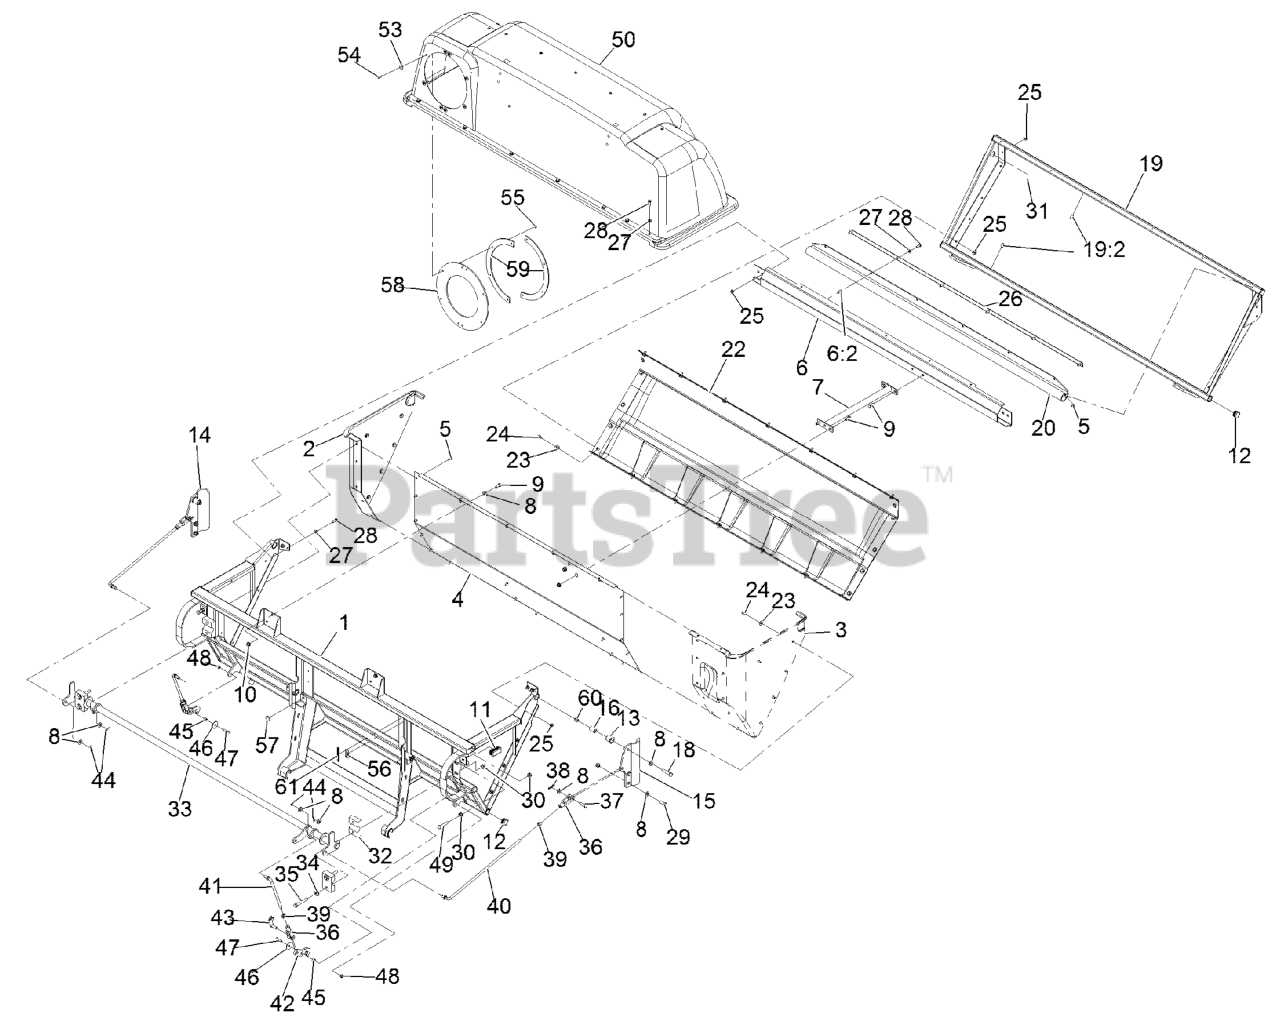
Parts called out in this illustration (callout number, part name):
2	PANEL-BAGGER, RH
3	PANEL-BAGGER, LH
4	SHEET-WALL
5	RIVET-BLIND
6	REAR CROSSMEMBER ASM
6:2	NUT-CLINCH
8	WASHER-FLAT
9	SCREW-HH
13	BUSHING
14	ARM-HINGE, RH
15	ARM-HINGE, LH
16	PIN-PIVOT, HINGE
18	SCREW-HH
19	DOOR ASM
19:2	NUT-CLINCH
20	SEAL-DOOR HINGE
22	BAG AND BOTTOM PANEL ASM
23	WASHER-FLAT
24	SCREW-HH
26	STRAP-HOLD DOWN
27	WASHER-FLAT
28	SCREW-HH
29	SCREW-HH
30	NUT-HHF, WHIZ
31	PLUG-DOME
33	LINK-INTERMEDIATE
34	WASHER-FLAT
35	SCREW-HH
36	YOKE-LINKAGE, BRAKE
37	PIN-CLEVIS
38	PIN-COTTER
39	NUT-HEX
40	LINK-HINGE
41	LINK-HANDLE
43	PIN-SPRING, CLEVIS
44	PIN-COTTER
46	WASHER-FLAT
47	SCREW-HH
48	NUT-LOCK, NI
49	SCREW-HH
50	ASM,HOOD DUMP
53	WASHER-FLAT
54	SCREW-PPH
55	NUT-LOCK, NI
56	Decal-Patent Ttco.Com
58	SEAL-TUBE
59	CLAMP-SEAL
60	NUT-LOCK, NI
61	DECAL-WARNING
